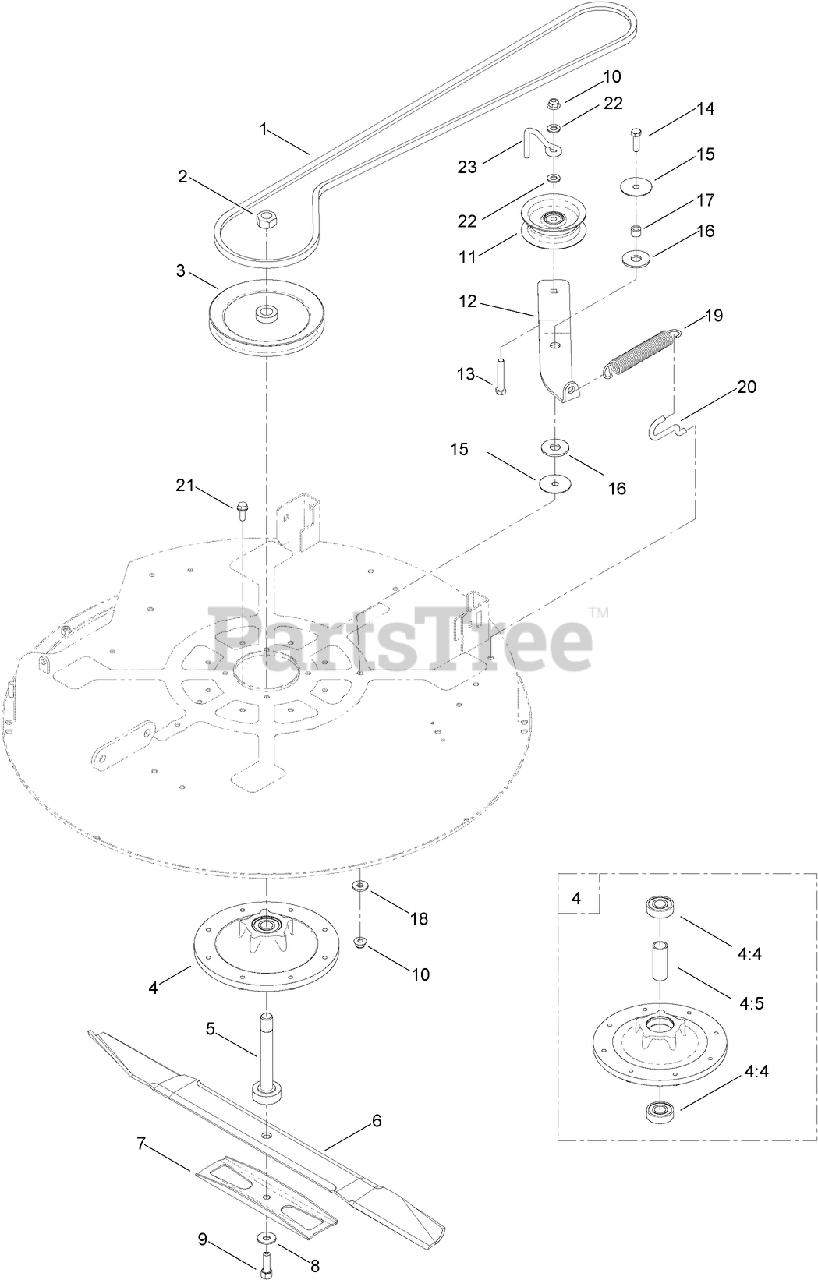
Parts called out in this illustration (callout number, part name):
1	V-BELT, 81.8 INCH
2	NUT-HEX
3	PULLEY-DECK
4	SPINDLE HOUSING ASM
4:4	BEARING-BALL
4:5	SPACER-BEARING
5	SHAFT-SPINDLE
6	BLADE-RECYCLER, 31.35 INCH
7	STIFFENER
8	WASHER-BELLEVILLE
9	SCREW-HH
10	NUT-HF, NI
12	ARM-IDLER
13	SCREW-HH
14	SCREW-HH
15	WASHER
16	WASHER-FRICTION, COMPOSITE
17	SPACER
18	WASHER-HARDENED
19	SPRING-EXTENSION
20	HOOK-RETURN, SPRING
21	SCREW-TAPTITE
22	WASHER-FLAT
23	GUIDE-IDLER, BELT
